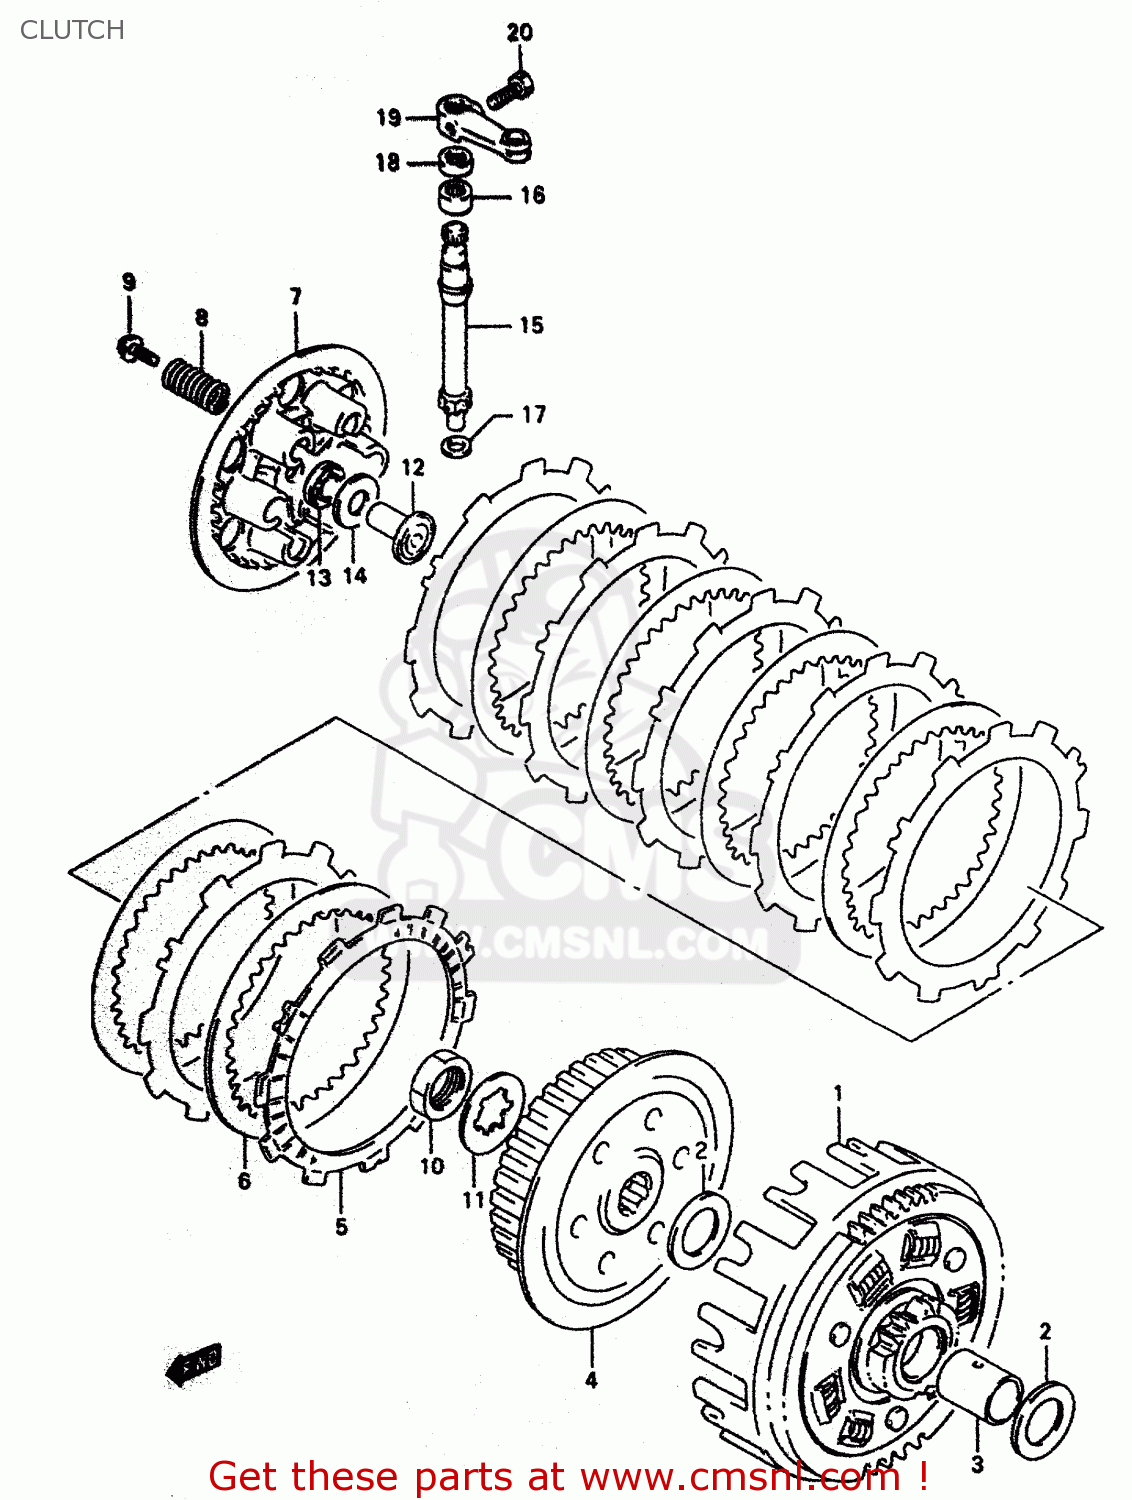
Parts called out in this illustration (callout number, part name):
1	GEAR ASSY,PRI DRIVEN(64/15
2	WASHER
3	SPACER(20X25X29)
4	HUB,CLUTCH SLEEVE
5	PLATE,CLUTCH DRIVE (NAS)
6	PLATE,CLUTCH DRIVEN(T:1.6) (NAS)
7	DISC,CLUTCH PRESSURE
8	SPRING
9	BOLT 5X16
10	NUT
11	WASHER,LOCK
12	RACK,CLUTCH RELEASE
13	BEARING(10X24X2)
14	WASHER
15	PINION,CLUTCH RELEASE
16	BEARING(12X16X10)
17	SHIM(8.8X14X1)
18	SEAL,OIL(10X17X5)
19	ARM,CLUTCH RELEASE
20	BOLT
